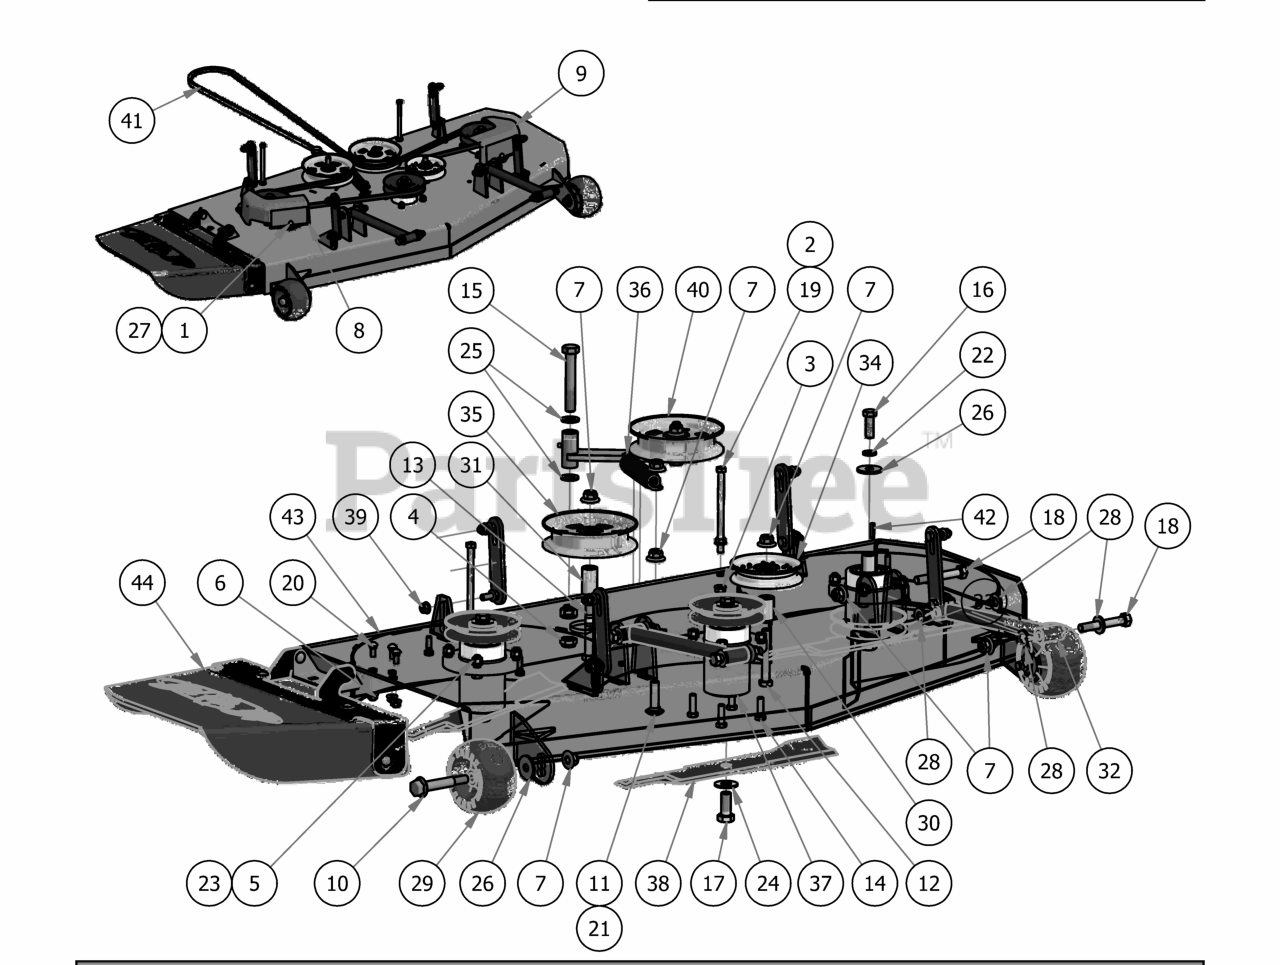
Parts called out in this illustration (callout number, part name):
1	Acorn nut-pulley Cover
2	3/8" Flange Nut
3	3/8" Nylock Flange Nut
4	5/8" Nylock (1/2 Jam)
5	3/8" Hex Nut
6	5/16" Nylon Flange Nut
7	1/2-13 Nylon Flange Nut
8	pulley cover chute side
9	pulley cover non-chute side
10	Deck Wheel Bolt
11	1/2 x 2" Carriage Bolt
12	1/2 x 3 1/2 Flange Bolt Grade 8
13	1/2" x 4" Bolt (Grade 8)
14	3/8" x 1 1/4" Hex Bolt
15	5/8" x 4" Hex Bolt
16	1/2"-20 x 1 1/2 - Grade 5 Fine Thread Bolt
17	5/8 x 1 1/2 Grade 8 Hex Bolt (Fine)
18	1/2-13 x 3 1/2 GR 5 Hex Bolt
19	3/8-16 x 5 1/2 Hex Bolt
20	5/16-18x3/4 carriage bolt
21	.517 Square Hole Round Washer
22	1/2" Lock Washer
23	3/8" Lock Washer
24	5/8'' Flat Washer
25	.630 ID Plastic Washer
26	1/2 Belleville Washer
27	.360 ID Plastic Washer-Black
28	.505 Nylon Spacer
29	Deck Wheel
30	Idler Pulley Standoff
31	1 3/4" Pulley Spacer
32	MZ/ZT Deck Locator
33	MZ Deck Pulley
34	4-3/4 Idler Pulley
35	5-3/4 Idler Pulley
36	Deck Idler Spring
37	Spindle Assembly-MZ
38	48" High Lift Fusion Blade
39	Deck Hanger Assembly
40	2017 54"/48" Deck Idler Assembly
41	B147 Deck Belt
42	3/16 x 1 Square Key
43	2017 48" MZ Deck-Welded Shell
44	MZ Discharge Chute Assembly
